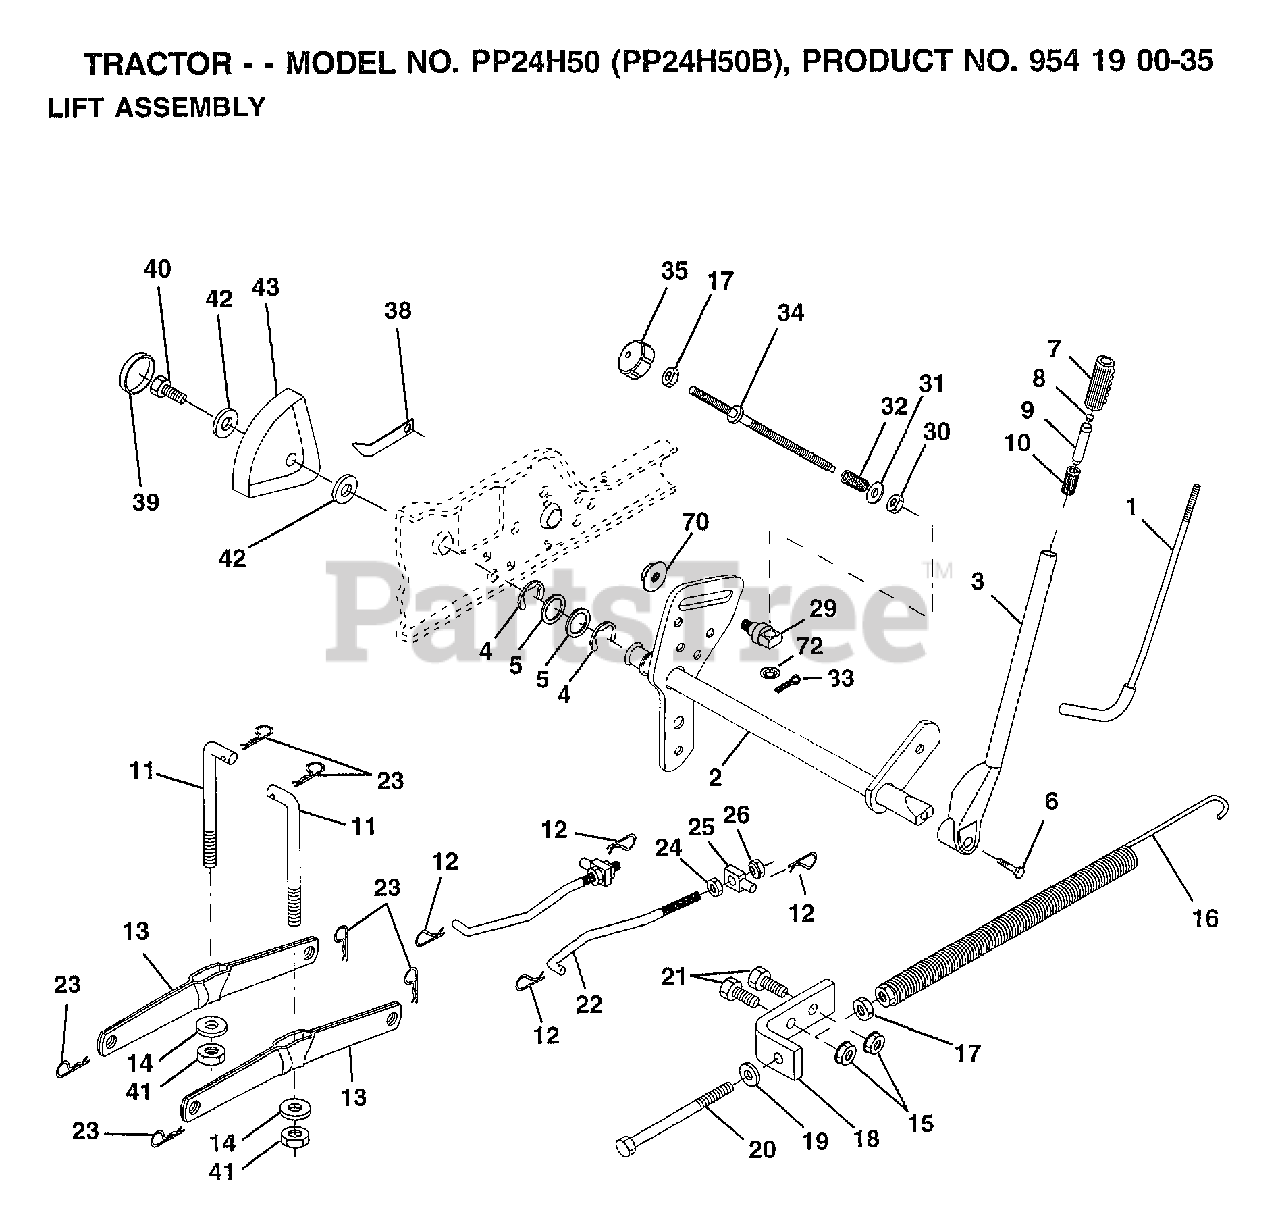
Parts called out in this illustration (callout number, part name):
1	LEVER ROD LT
2	SHAFT.ASM.LIFT.VGT
3	LEVER.ASM.LIFT.RH
4	E-RING
5	WASHER
6	"BOLT,HEX"
7	GRIP
10	SPRING T
11	LINK.LIFT.MWR.VGT
12	RETAINER SPRING
13	ARM SUSP REAR
14	BEARING PVT LH
17	NUT
18	BRACKET SPRING AS
19	WASHER
20	BOLT-ADJ SPRING T
21	BOLT
22	LINK.FRONT
24	NUT
25	TRUNION
26	NUT.LK.W/WSH.1/2.
29	TRUNNION
30	NUT T
31	WASHER
32	SPRING.COMP.INF.H
34	ROD.ADJ.LIFT
35	KNOB INF 3/8-16
38	POINTER HEIGHT INDICATOR
39	"PLUG,HOLE"
40	SCREW
41	NUT.CROWNLOCK.3/8
42	WASHER
43	HEIGHT INDICATOR
70	NUT.HXFLG.LOCK.
72	NUT PUSH M
